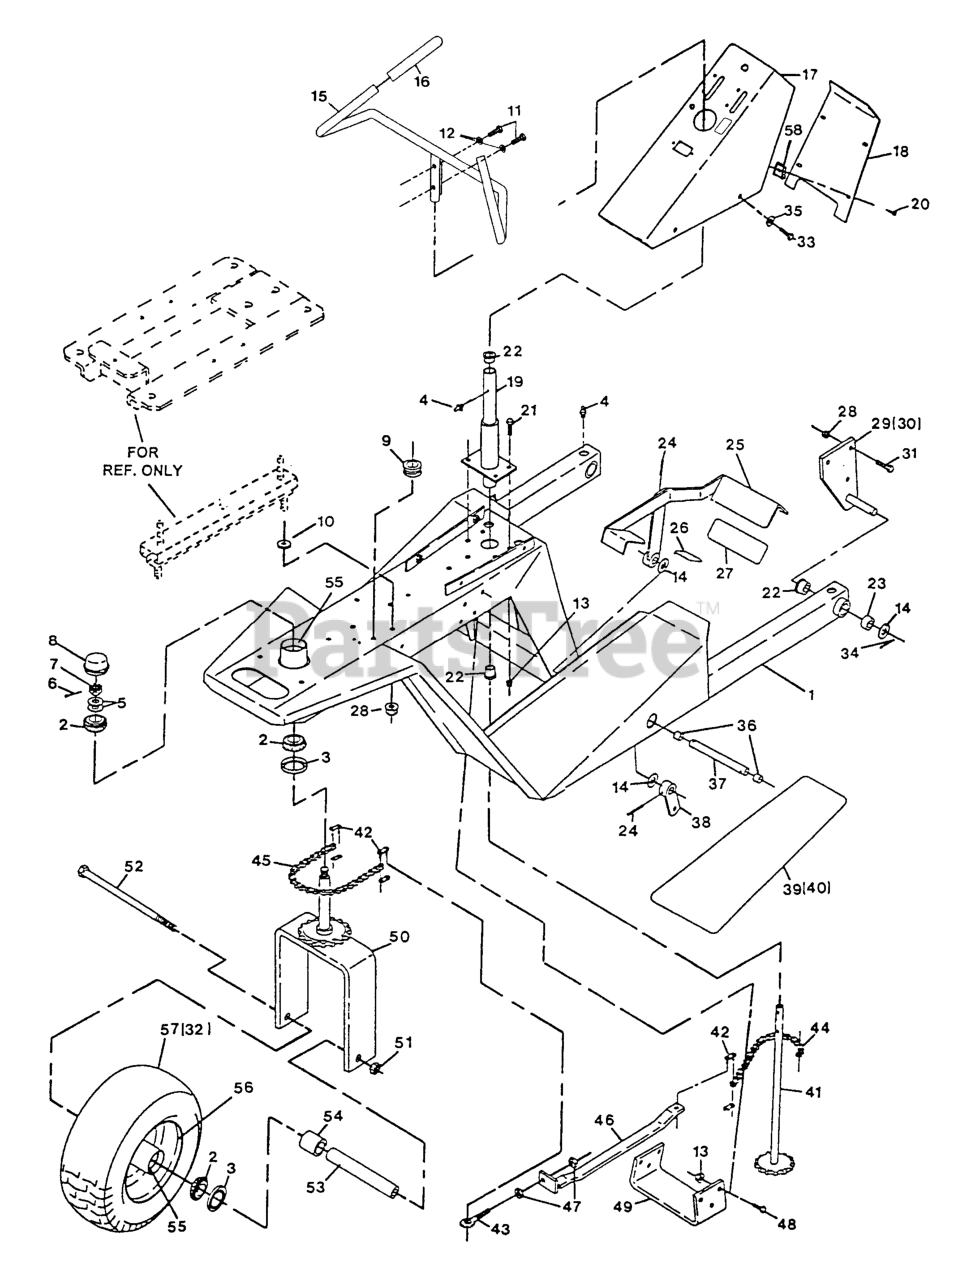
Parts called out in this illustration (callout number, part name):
1	ASM,RIDER FRAME W/DECALS
2	Cone-Bearing Tapered Roller
3	SEAL-GREASE
4	FITTING-GREASE
5	WASHER-FLAT
6	PIN-COTTER
7	NUT-HEX, SLOTTED
8	CAP-GREASE
9	GROMMET
10	WASHER-FLAT
11	SCREW-HH
12	WASHER-BELLEVILLE
13	NUT-HHF, WHIZ
15	WLD,HANDLE BAR
17	CONSOLE,TR W/DECALS
18	PLATE-CONSOLE, FRONT
19	WLD,STEERING POST
20	SCREW-HWH
21	SCREW-HH
23	SLEEVE,BEARING
24	PIN,ROLL
25	PEDAL,FOOT W/PADS
27	PAD,ANTISKID
29	WLD,BRACKET PIVOT RH
31	SCREW-HH
32	TIRE ONLY 8NHS
33	SCREW-HH
35	WASHER-FLAT
37	Shaft, Foot Pedal
38	WLD,FOOT PEDAL LEVER
39	PAD,ANTISKID RH
41	WLD,STEERING SHAFT
43	EYEBOLT, RH
47	NUT-JAM
48	SCREW-HH
49	STOP,ACTUATOR
52	SCRW,CAP HH
53	BUSHING, WHEEL - PLT
54	SPACER,WHEEL SHORT
55	CUP-BEARING
56	WHEEL 8.00 W/HUB
57	ASM,WHEEL & TIRE
58	CLIP,SGLTHRD TYPU
